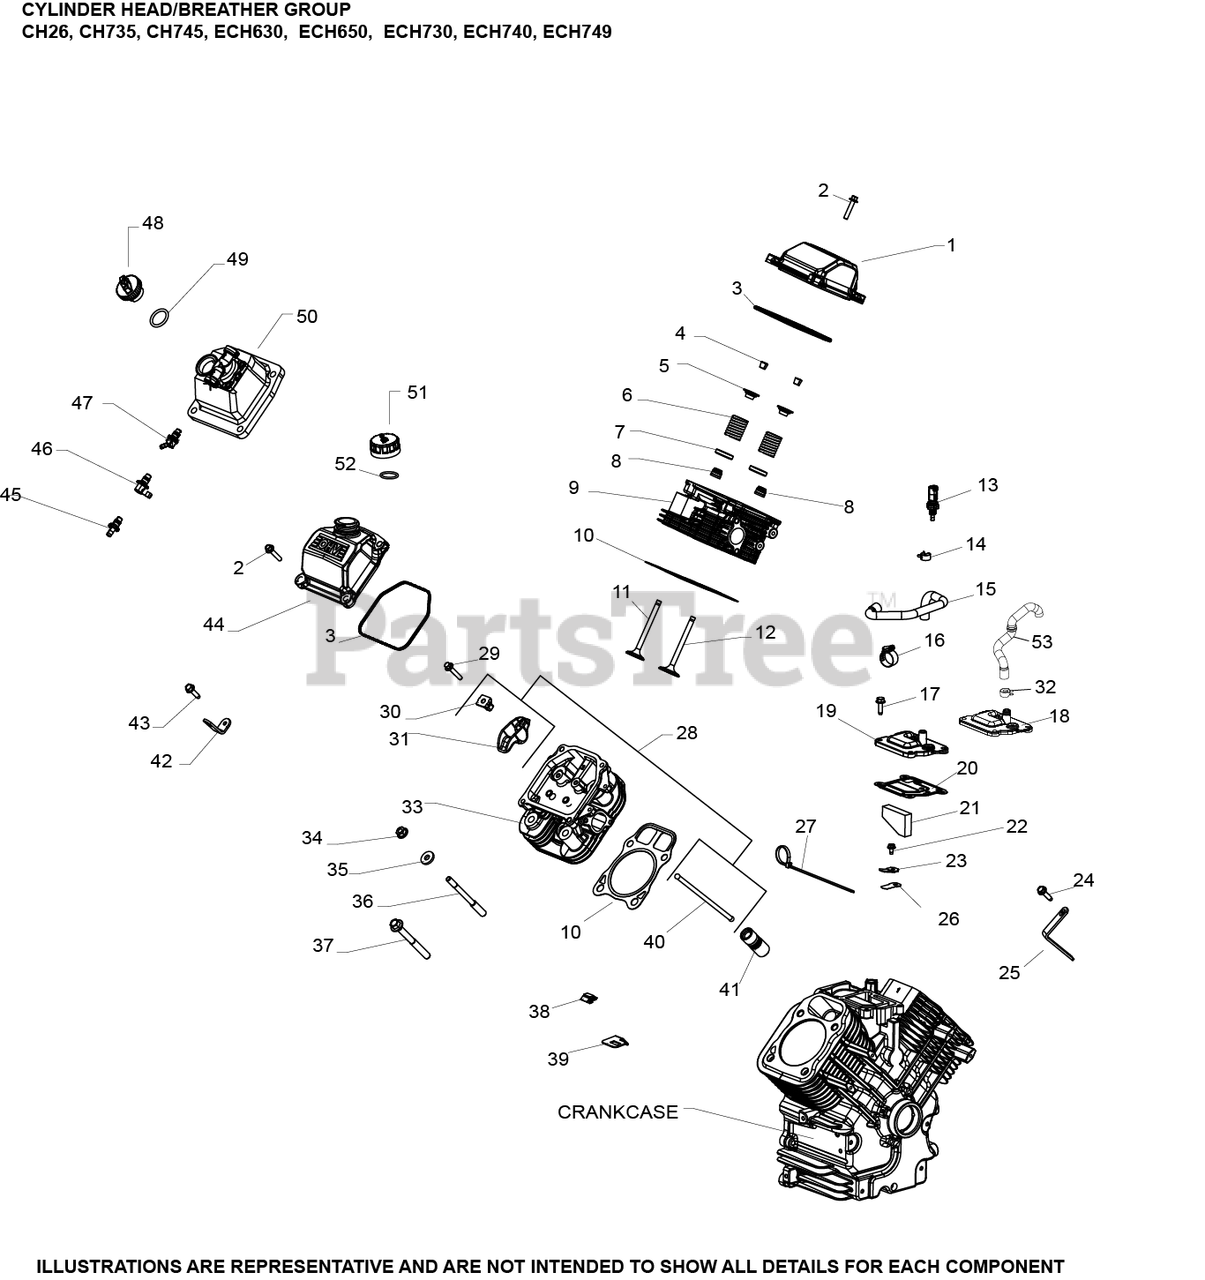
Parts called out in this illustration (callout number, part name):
1	KIT, VALVE COVER-PLAIN
2	SCREW, FLG M6X1.0X30
3	O-RING (YELLOW), VALVE COVER
4	KIT, RETAINER
5	CAP, VALVE SPRING
6	SPRING, VALVE
7	RETAINER, SPRING
8	SEAL, VALVE STEM - (#2503214S)
9	KIT, CYLINDER HEAD #1 USE 24 318 155-S
10	CYL HEAD GASKET KIT-USE 24 841 04-S
11	VALVE, EXHAUST (STD) - USE 32 016 01-S
11	VALVE, EXHAUST (.25)
12	VALVE, INTAKE (STD)
12	VALVE, INTAKE (.25)
13	SENSOR, TEMPERATURE
14	CLAMP, BAND SPRING HOSE-(#2523737S)
15	HOSE, BREATHER - EFI HORIZONTAL
16	CLAMP, HOSE-USE 25 237 32-S
17	SCREW,FLG THD FRM M6X1.0X20-(#25086396S)
18	KIT, BREATHER COVER-USE 24 096 132-S
20	GASKET, BREATHER
21	FILTER, BREATHER
22	SCREW, FLG THD FRM M5X.8X10
23	RETAINER, REED
24	SCREW,FLG THD FRM M6X1.0X25-(#25086395S)
25	STRAP, LIFTING-USE 25 445 03-S
26	REED, BREATHER
28	KIT, VALVE TRAIN
29	SCREW, FLG M6X1.0X34
30	PIVOT, ROCKER ARM
31	ARM, ROCKER
33	KIT, CYLINDER HEAD #2 USE 24 318 156-S
34	NUT, FLG M8X1.25
35	WASHER, FLAT 8.6 MM
36	STUD, M8X1.25
38	CLIP, O2 SENSOR
39	BRACKET, OXYGEN SENSOR
40	ROD, PUSH
41	LIFTER, VALVE HYDRAULIC-USE 25 351 10-S
42	STRAP, LIFTING
45	KIT, STRAIGHT FITTING
46	KIT, 90 DEG. FITTING
48	CAP ASSY, OIL FILL (YELLOW)
50	KIT, VALVE COVER-FUEL PUMP
